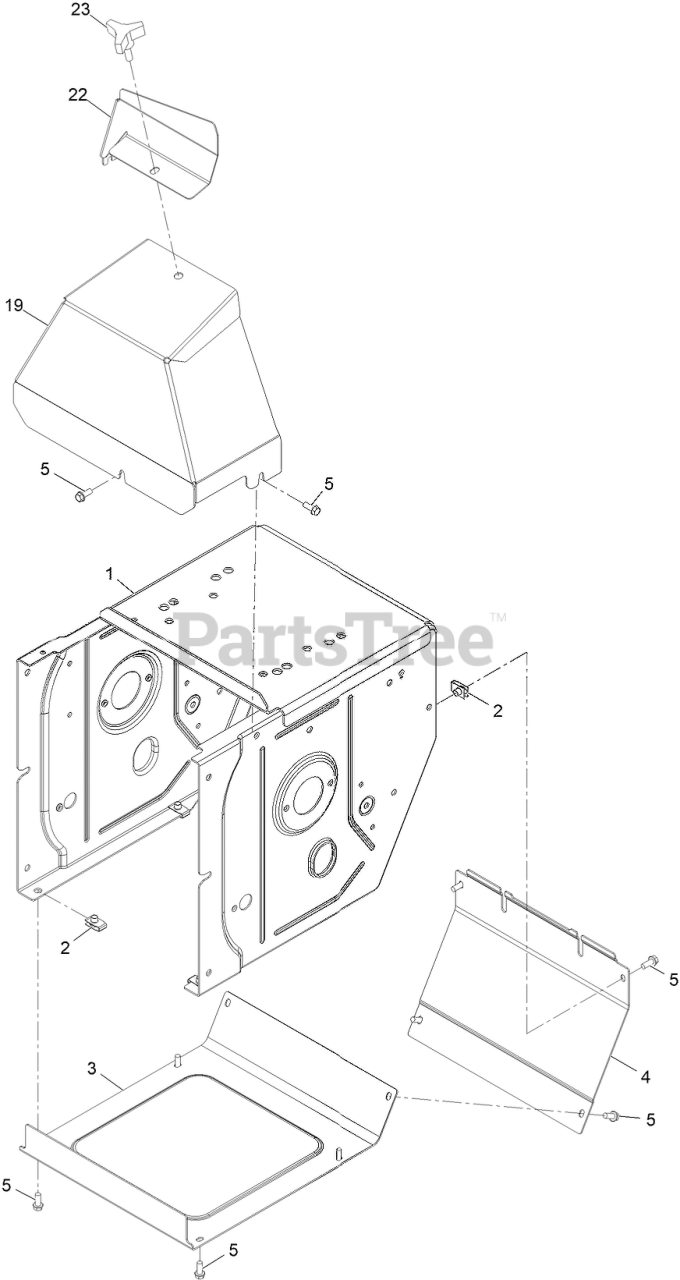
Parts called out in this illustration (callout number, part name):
1	FRAME, TRACTION
3	COVER-BOTTOM
4	COVER-REAR
5	SCREW-HWH
19	COVER - BELT
22	SHIELD-ICE, KC CH270
